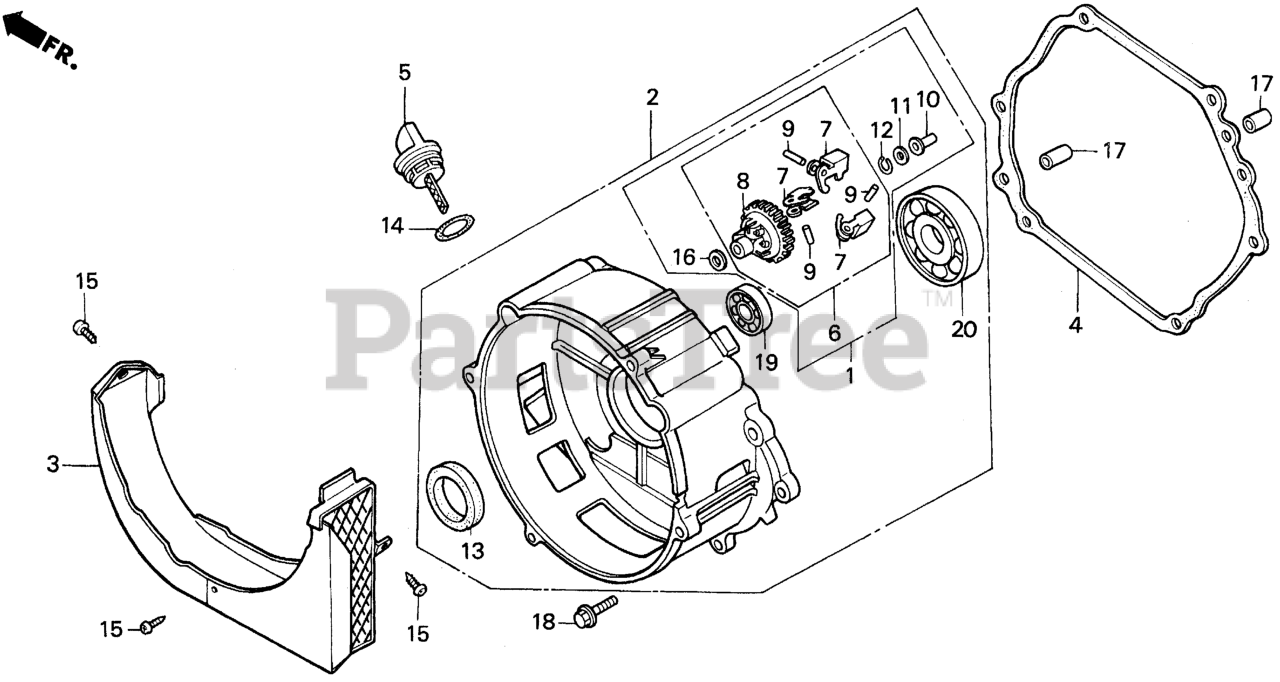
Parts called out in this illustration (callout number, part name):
1	GOVERNOR KIT Use from Engine SN 2086153.
1	GOVERNOR KIT Use up to Engine SN 2086152.
2	COVER ASSY., CRANKCASE (E-TYPE)
2	COVER ASSY., CRANKCASE (E-TYPE) (NOT AVAILABLE)
2	COVER ASSY., CRANKCASE
3	COVER, DUCT
4	GASKET, CASE COVER
4	GASKET, CASE COVER Use up to Engine SN 2949254.
5	CAP, OIL FILLER
6	GOVERNOR ASSY.
7	WEIGHT, GOVERNOR
8	HOLDER, GOVERNOR WEIGHT
9	PIN, GOVERNOR WEIGHT
10	SLIDER, GOVERNOR
11	WASHER (6X16)
12	CLIP, GOVERNOR HOLDER
13	OIL SEAL (35X52X8)
14	O-RING (26X2.7)
15	SCREW, TAPPING (5X10)
16	WASHER, PLAIN (6MM)
17	PIN, DOWEL (8X12)
17	PIN A, DOWEL (8X12)
18	BOLT, FLANGE (8X40) Use up to Engine SN 1003236.
19	BEARING, RADIAL BALL (6202)
20	BEARING, RADIAL BALL (6207)
